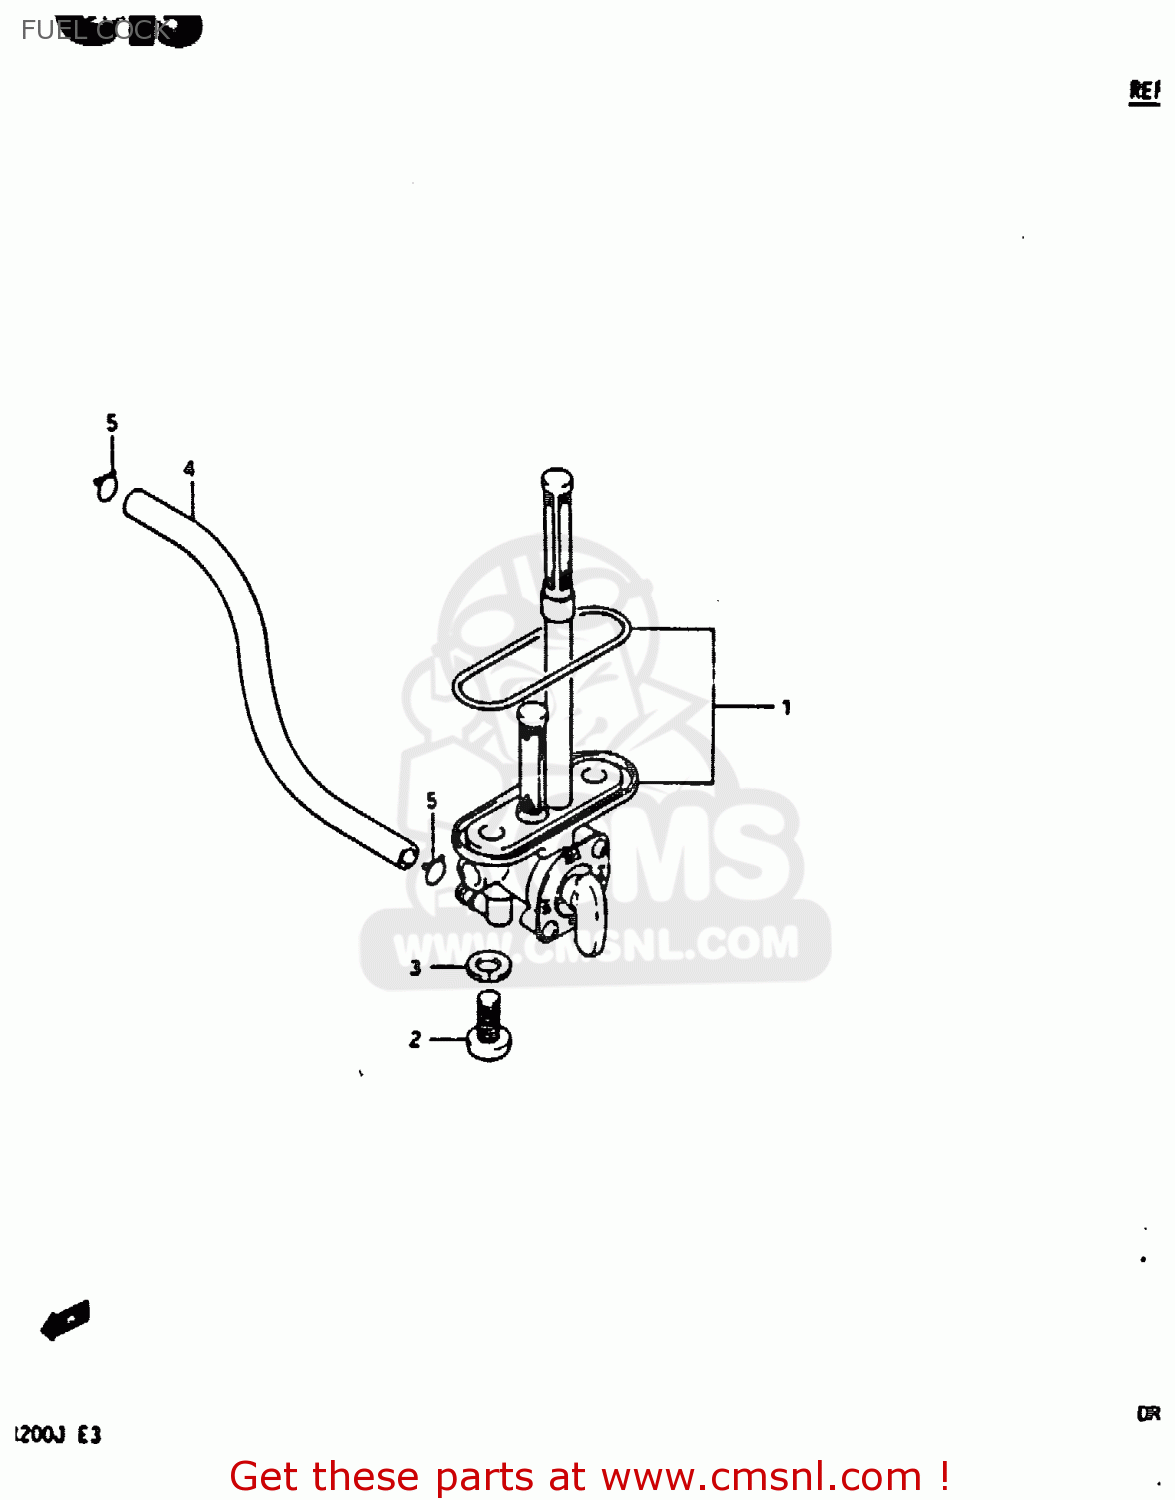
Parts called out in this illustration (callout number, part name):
1	COCK ASSY,FUEL
2	SCREW
3	WASHER,LOCK
4	HOSE
5	CLIP
